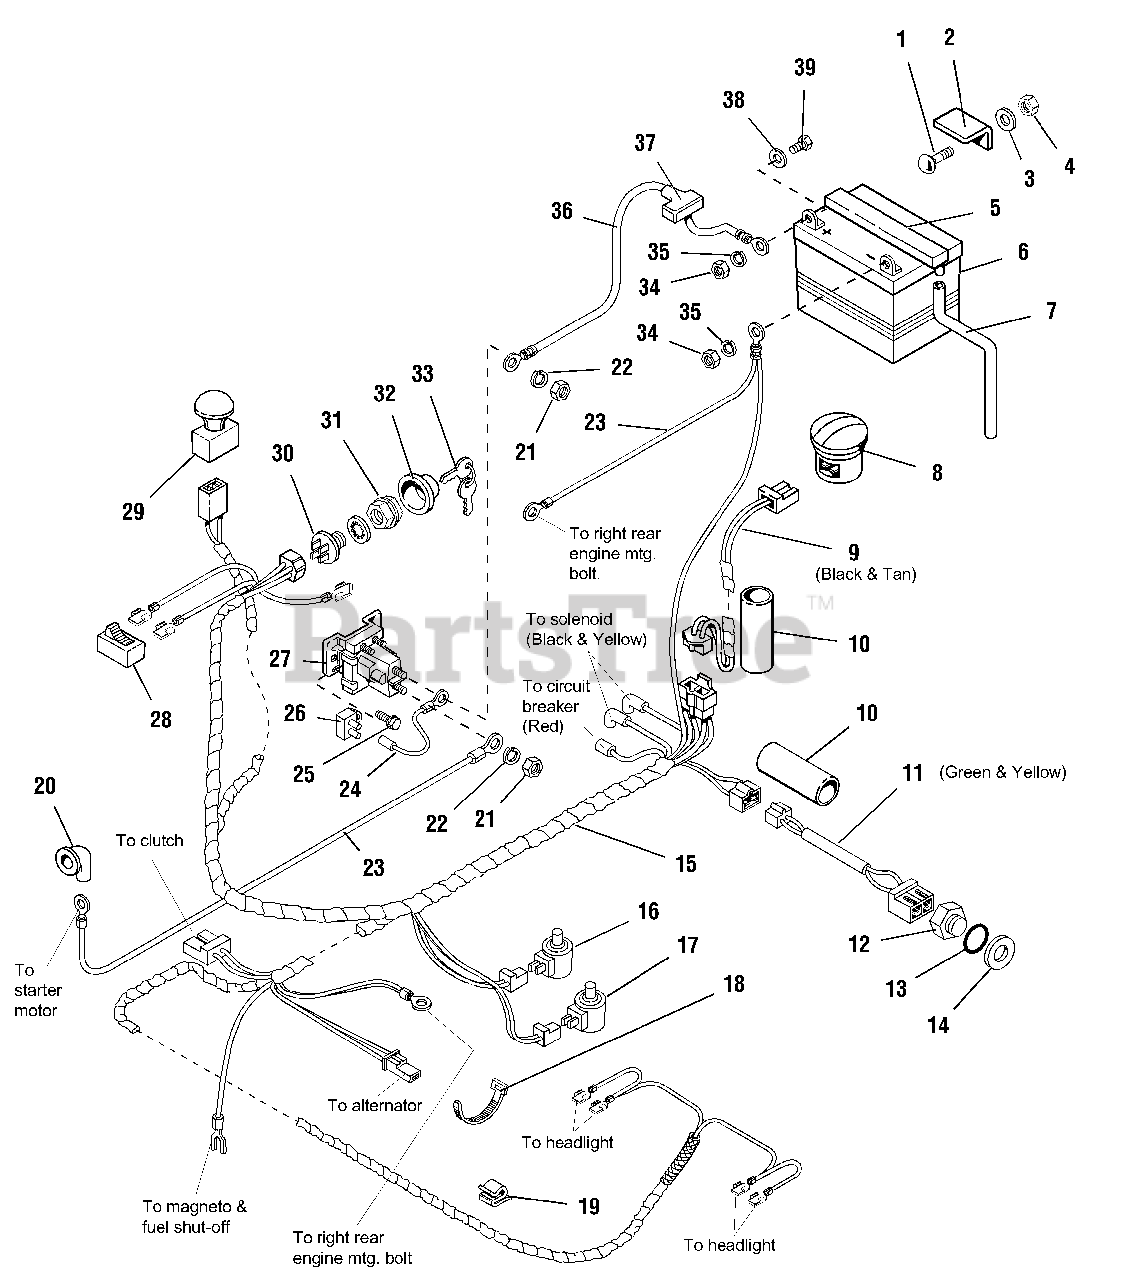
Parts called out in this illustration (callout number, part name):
1	CARRIAGE BOLT, 5/16-18 x 3/4
2	CLAMP, Battery
3	WASHER, Plain, 5/16
4	NUT, Hex, Nylon Lock, 5/16-18
5	CAP, Vent, Battery
7	HOSE, Drain
8	SWITCH, Seat
9	WIRE ASSY., Seat Switch
10	TUBE, Shrink
11	WIRE ASSY., Transmission
12	SWITCH, Transmission
13	SEAL, O-Ring
14	WASHER, 5/8
15	WIRING HARNESS
16	SWITCH, Pedal, N.C., Gray
17	SWITCH, Pedal, N.O., Black
19	CLIP, Wire
20	COVER, Terminal
21	NUT, Hex, 5/16-24 NF
22	LOCKWASHER, 5/16
23	CABLE
25	SCREW, Taptite, 1-20 x 5/8
26	CIRCUIT BREAKER
27	SOLENOID
28	SWITCH, Headlights
29	SWITCH, PTO
30	SWITCH, Ignition, 6-Pole
31	NUT, Hex, Flange, 5/8-8
32	COVER, Ignition
33	KEY, Ignition
34	NUT, Hex, 1/4-20
35	LOCKWASHER, 1/4
36	CABLE, Battery, Positive
37	BOOT, Insulator
38	WASHER, 1/4
39	CAPSCREW, Hex Hd., 1/4-20 x 3/4
